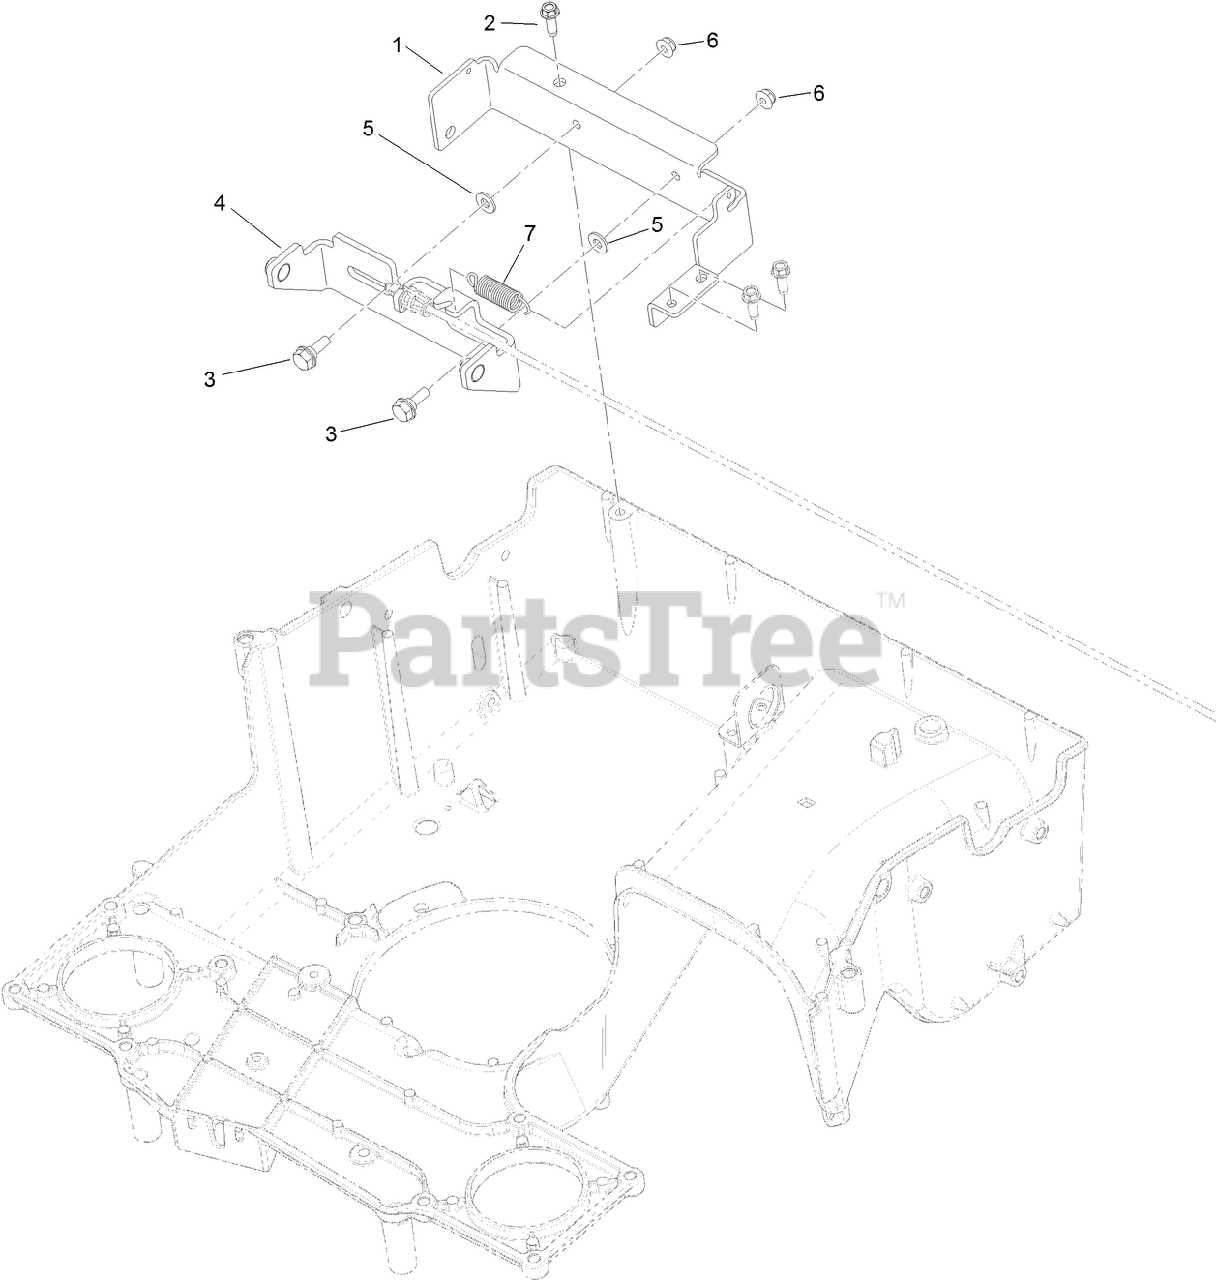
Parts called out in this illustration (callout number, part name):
1	BRACKET
2	SCREW-HWHTF
3	SCREW-SHOULDER, HHF
4	BRAKE ASM
5	WASHER-FLAT
6	NUT-HF
7	SPRING-EXTENSION
